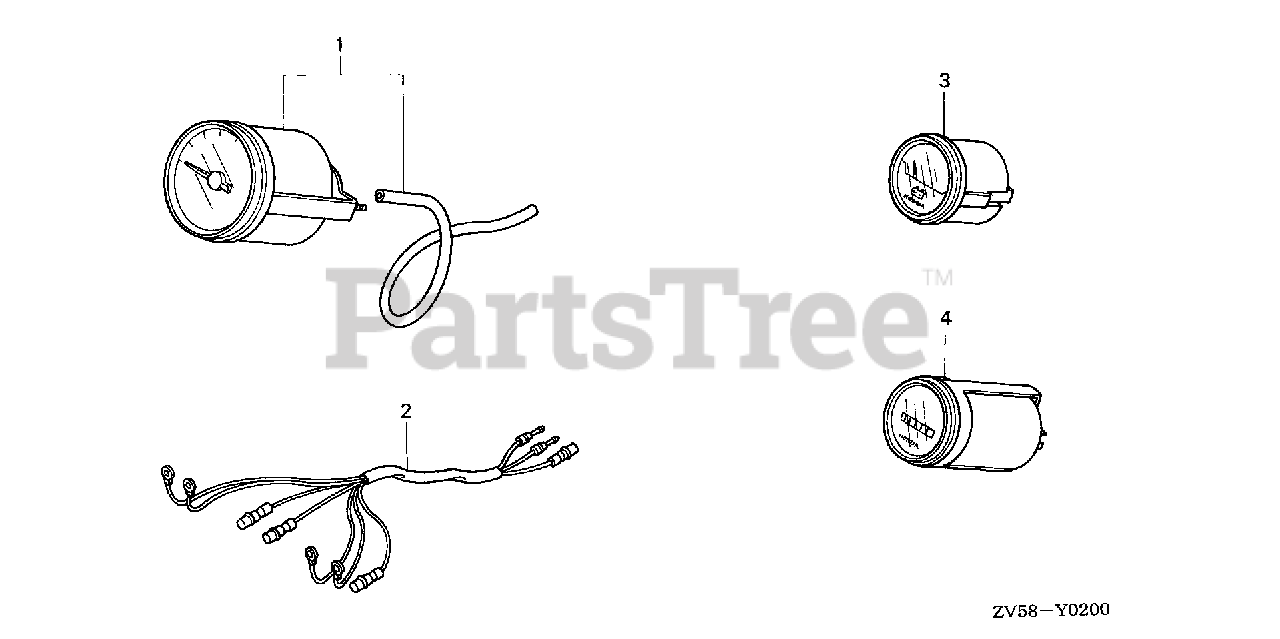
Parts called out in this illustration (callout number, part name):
1	SPEEDOMETER KIT
2	HARNESS ASSY., METER (B)
3	METER ASSY., VOLT (NOT AVAILABLE)
4	METER ASSY., HOUR L.C.D.
